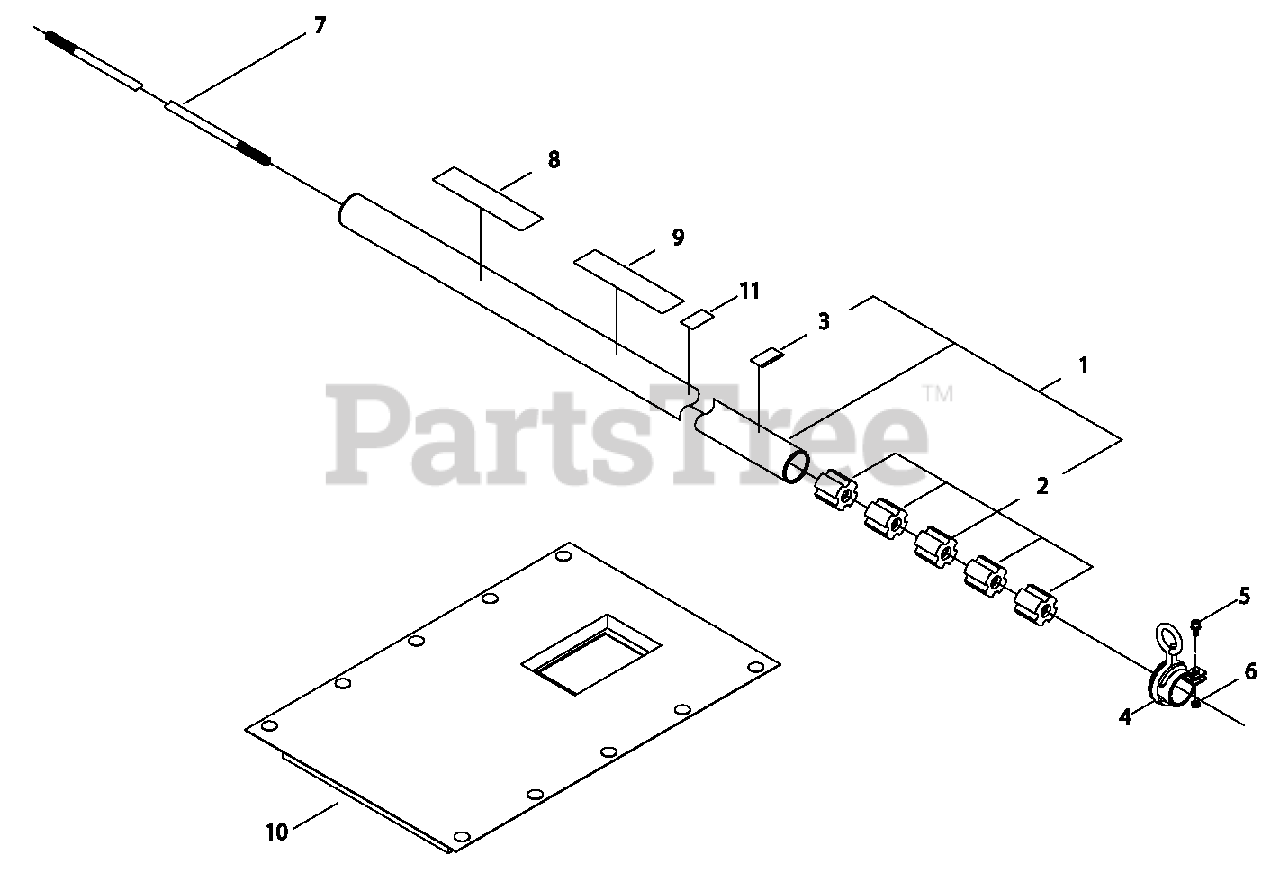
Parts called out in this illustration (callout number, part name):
1	MAIN PIPE ASSY
2	BUSHING
3	LABEL - ALIGNMENT
4	HANGER ASSY
5	SCREW - 5X12
6	NUT - 5
7	DRIVESHAFT - SOLID
8	LABEL - CAUTION
9	LABEL - SHINDAIWA PROFESSIONAL
10	PROTECTOR
11	LABEL - HANDLE LOCATION
